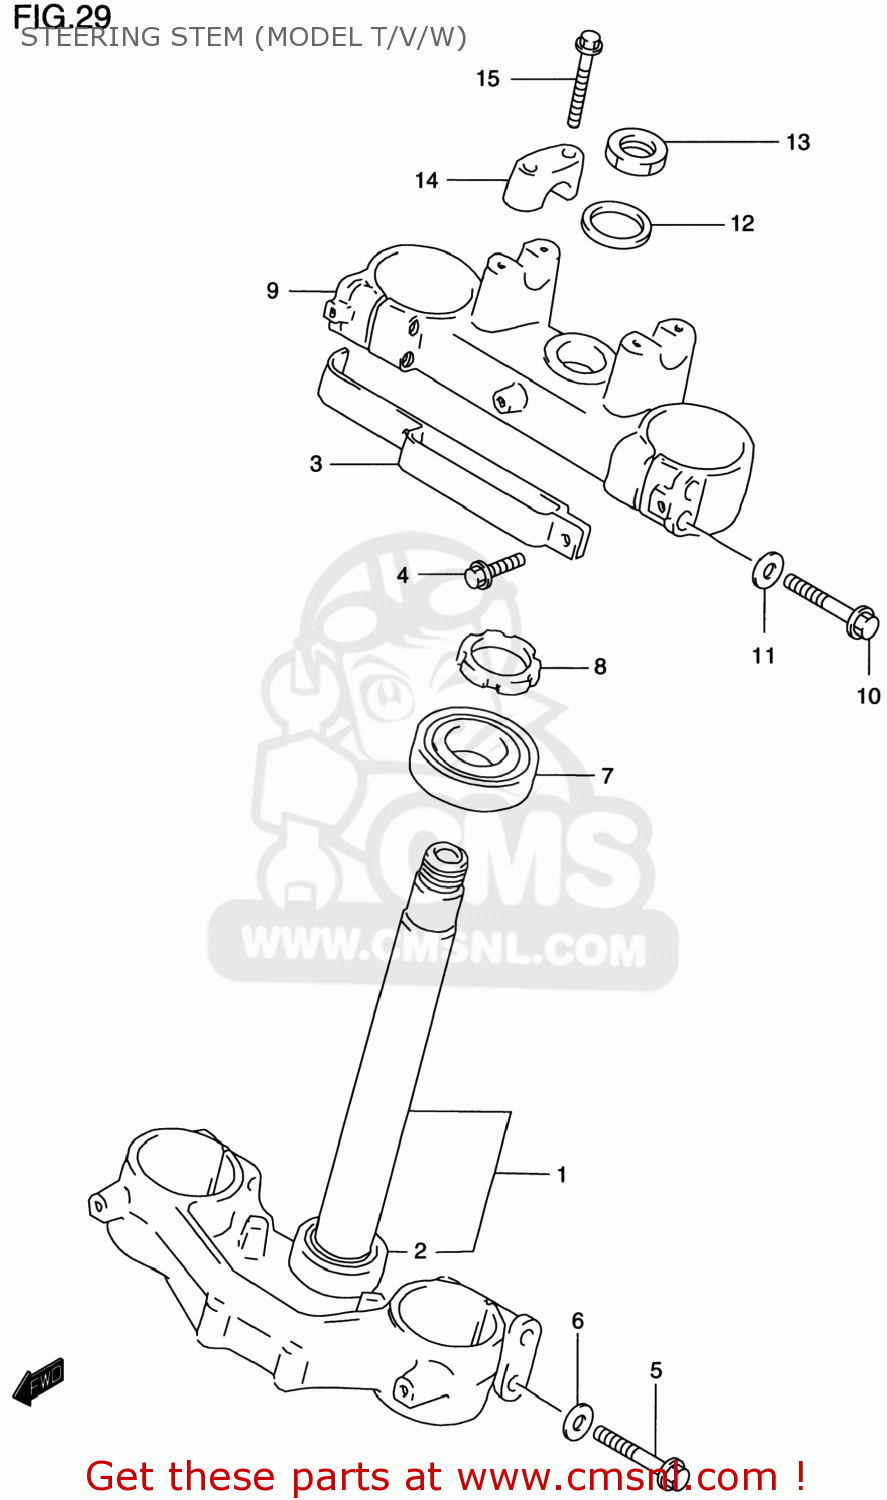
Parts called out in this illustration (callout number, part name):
1	STEM,STEERING
2	BEARING(30X52X16)
3	GUIDE,FR BRAKE HOSE
4	BOLT,PROTECTOR(6X10)
5	BOLT
6	WASHER
7	BEARING(30X52X16)
8	NUT,STEERING
9	HEAD,STEERING STEM
10	BOLT
11	WASHER
12	WASHER,STEM HEAD
13	NUT,STEM HEAD
14	HOLDER,HANDLEBAR
15	BOLT,HANDLE HOLDER(8X35)
